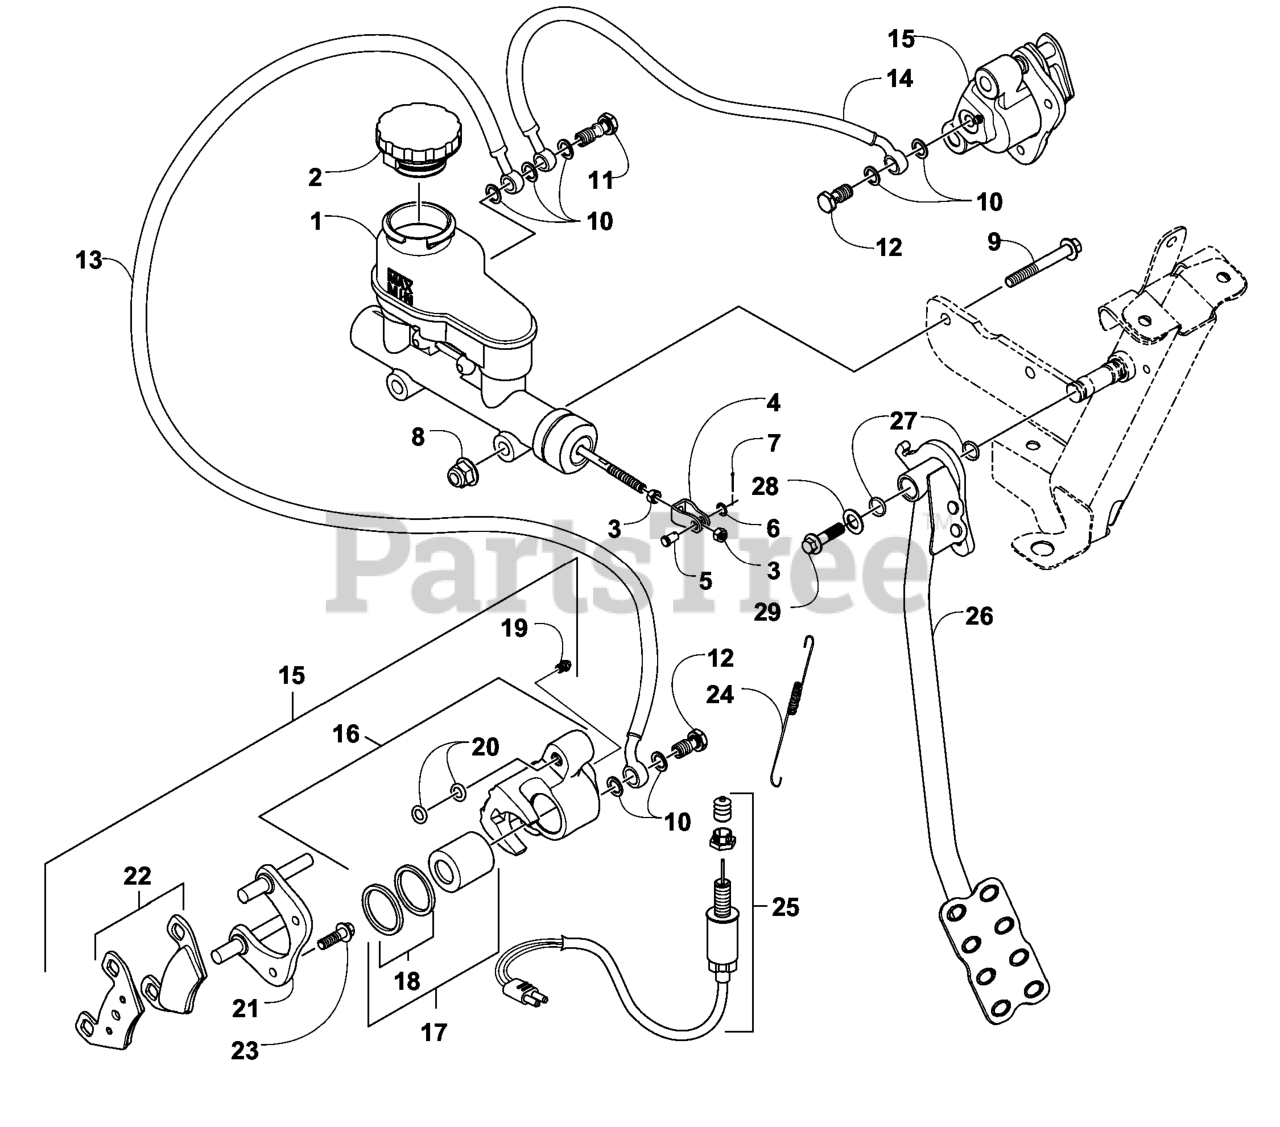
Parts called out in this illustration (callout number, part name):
1	CYLINDER
2	KIT-SERVICE CAP, TANDEM M
3	NUT-JAM
5	PIN-CLEVIS
6	WASHER-FLAT
7	PIN-COTTER
8	NUT-HHF, LOCK, (NI)
9	SCREW-HFH
10	WASHER-CRUSH
11	BOLT-BANJO FITTING, DOUBL
12	BOLT-BANJO FITTING
13	HOSE-BRAKE, FRONT
14	HOSE-BRAKE, FRONT RH
15	KIT-CALIPER, FULL ASM (RH
15	KIT-CALIPER, FULL ASM (LH
16	KIT-HOUSING (PISTONS, SEA
18	SEAL SET
19	BLEEDER-CALIPER
21	ARM - IDLER
22	KIT-BRAKE PAD (SET)
23	SCREW-HFH
24	SPRING-BRAKE SWITCH
25	SWITCH-BRAKE, FOOT
26	PEDAL-BRAKE
28	WASHER-FLAT, HARDENED
29	SCREW-HFH
